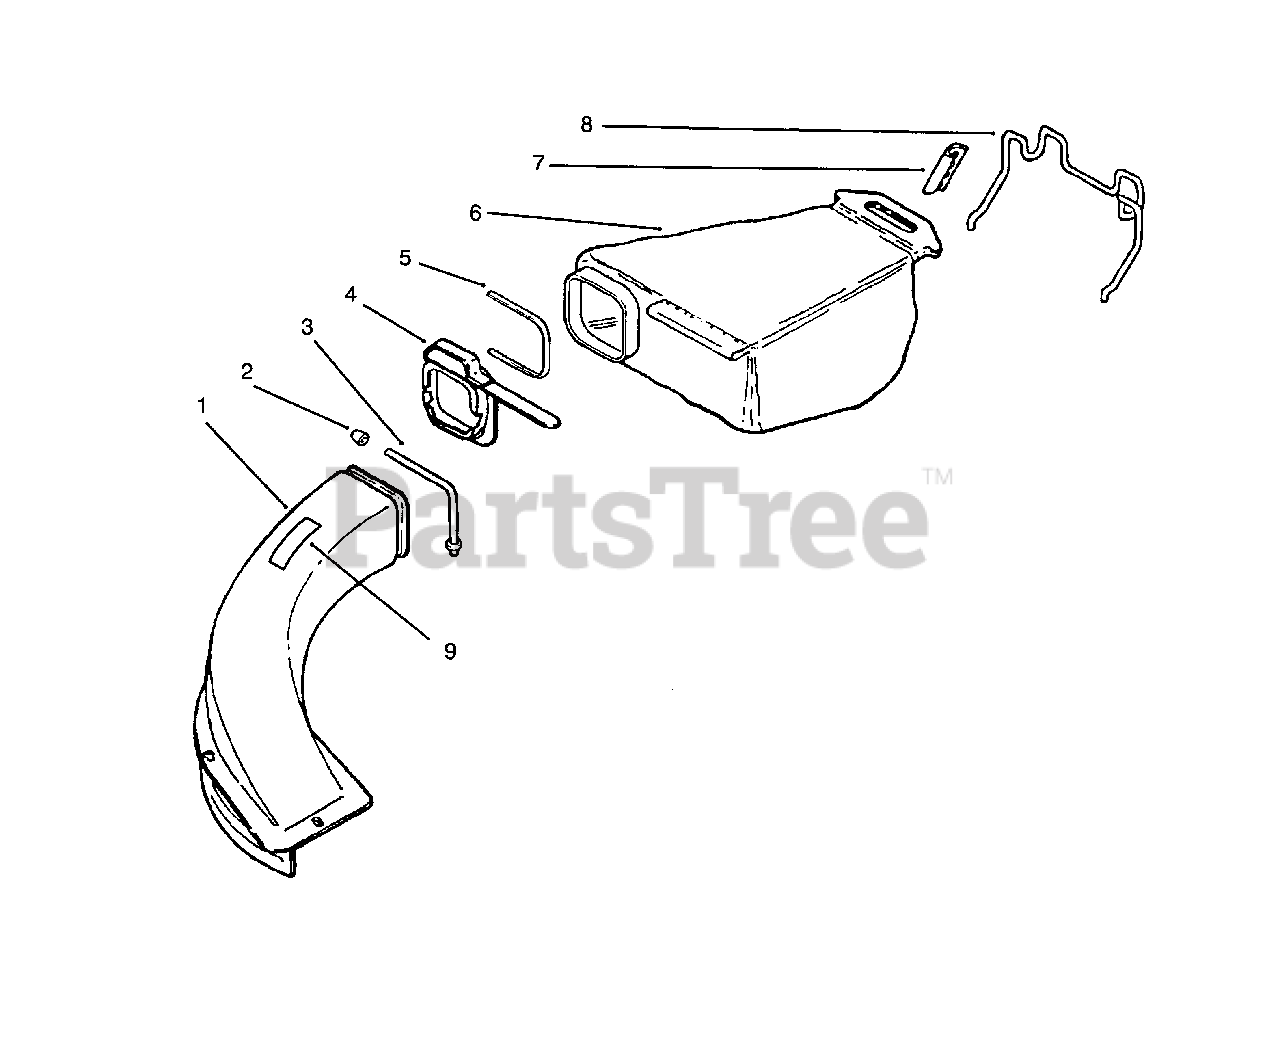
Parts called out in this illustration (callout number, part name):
1	Chute & support Assembly (Incl. Ref. #2, 3 & 9)
2	Nut-Cap
3	Chute Support
4	Adaptor Assembly
5	Tie Strap
6	Bag Assembly
7	Hanger Clamp
8	Wide Hanger
9	Decal-Danger
